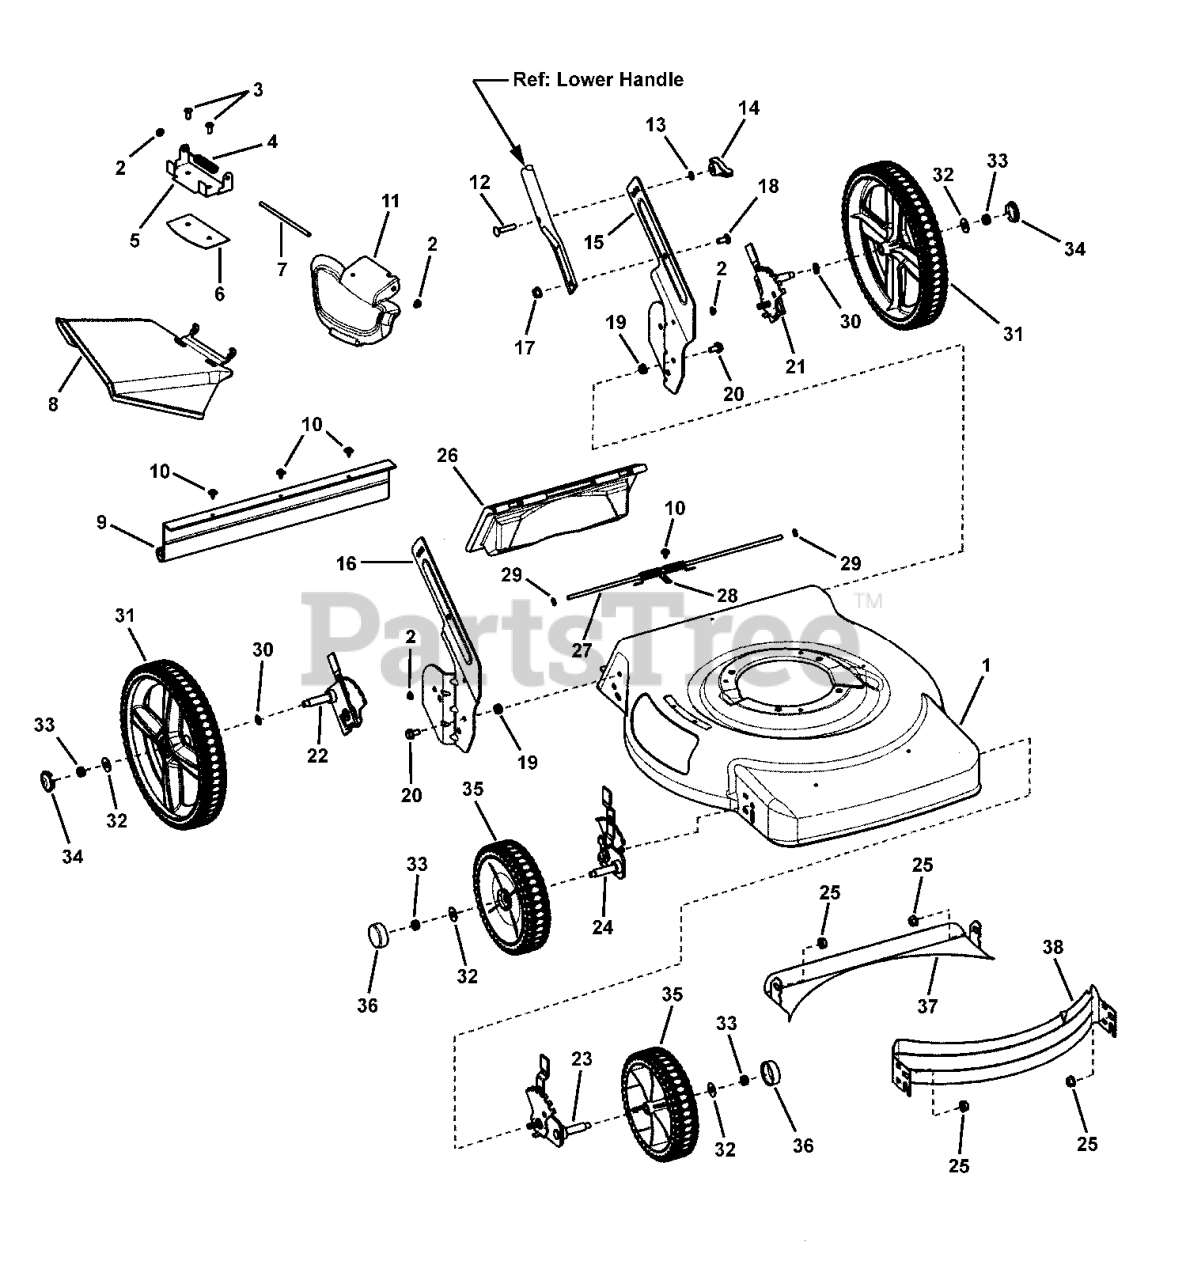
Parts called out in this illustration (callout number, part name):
1	DECK, 22" Walk, Push 3-N-1
2	PUSHNUT, 1/4"
3	SCREW, 1/4-20 x 11/16" Pan Head Self-Tap - Torx
4	SPRING, Chute - Torsion
5	BRACKET, Chute
6	PLATE, Mulch, 22" RB Scott's
7	ROD, Chute Pivot - 1/4" Dia. x 5.55"
8	SIDE CHUTE, Plastic, Black
9	GUARD, Rear 22" Hi-Wheel
10	SCREW, #10-24 x 1/2" Hex Washer Self-Tap - Sems
11	COVER, Mulch, Plastic, Black
12	BOLT, 5/16-18 x 1-1/2" Square Neck Carriage
13	WASHER, 5/16" Internal Tooth Lock
14	KNOB, 5/16-18 Wing - Black
15	BRACKET, Lower Handle, LH, 22" WBM, Hi-Wheel
16	BRACKET, Lower Handle, RH, 22" WBM, Hi-Wheel
17	NUT, 5/16-18 Large Flange Center Lock
18	BOLT 5/16-18 x 3/4" Round Head Short Square Neck
19	NUT, 3/8-16 Hex Center Lock, YZ
20	BOLT, 5/16-18 x 5/8" Hex Flange Lock
21	ASSY, Height-of-Cut, Left Rear, 7 Position
22	ASSY, Height-of-Cut, Right Rear, 7 Position
23	ASSY, Height-of-Cut, Left Front, 7 Position
24	ASSY, Height-of-Cut, Right Front, 7 Position
25	NUT, 3/8-16 Hex Flange Lock, GR 5
26	DOOR, Rear Discharge, 22" Walk Mower
27	ROD, Pivot, Rear Door - 1/4" Dia. X 17-1/2"
28	SPRING, Torsion, Rear Door, 22" Walk Mower
29	CAP, Retainer
30	WASHER, .531 x .781 3-Wave
31	ASSY, Wheel, 12" x 2" Idle, NB, Murray Tread, Gray
32	WASHER, 1" O.D. x .387 I.D. Flat
33	NUT, 5/16-18 Flange Lock
34	HUBCAP, 12" Wheel, Murray Gray
35	ASSY, Wheel 8" x 2" Idle, NB Murray Tread, Gray
36	HUBCAP, Round, Black
37	BAFFLE, Rear, 22" Deck
38	BAFFLE, Front, 22" WBM
